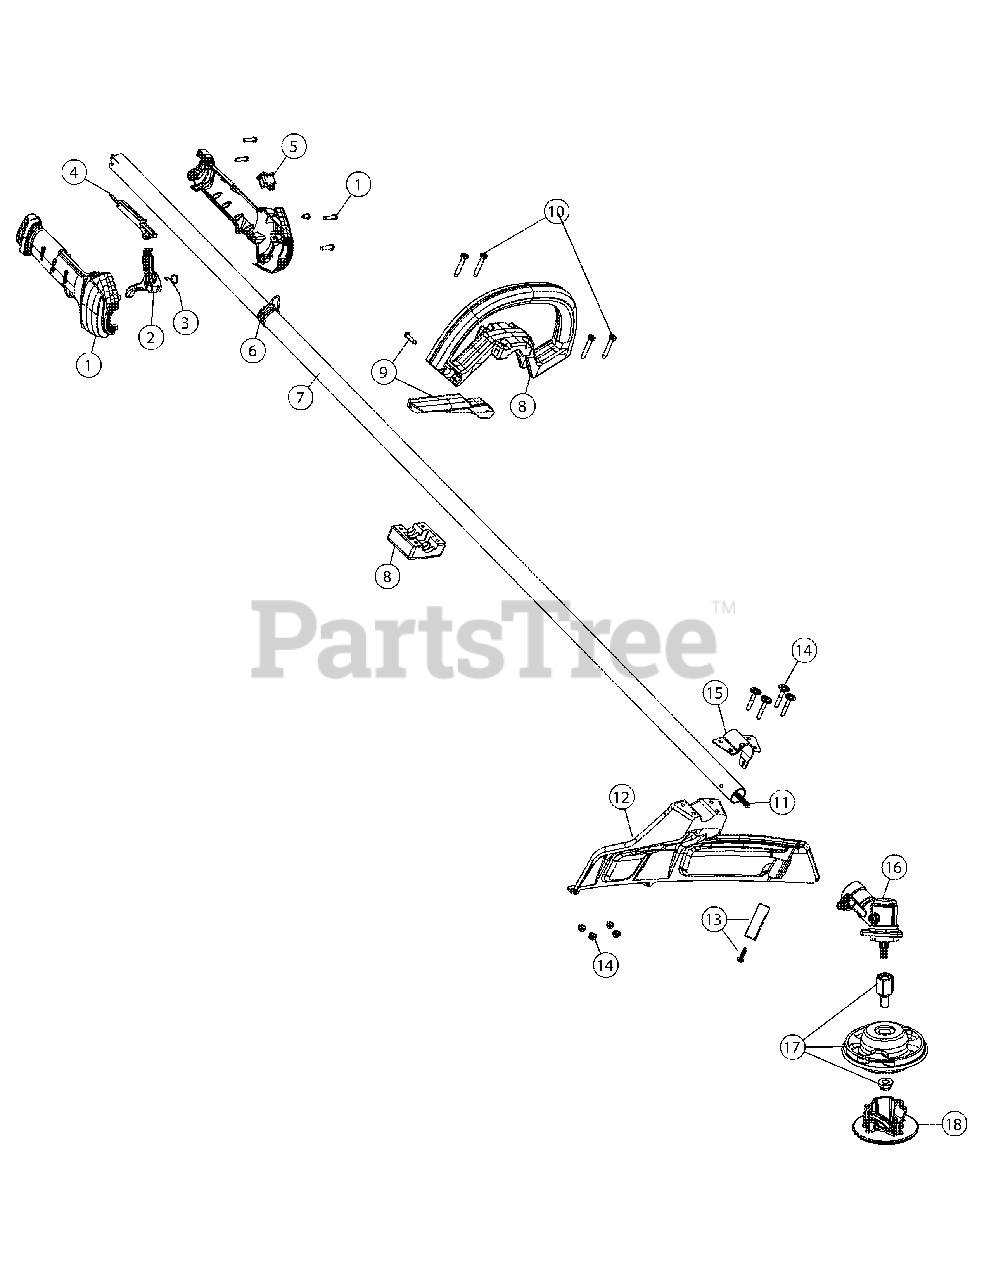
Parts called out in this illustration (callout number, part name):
1	Throttle Housing Assembly
2	Throttle Trigger
3	Spring
4	Throttle Lock-out
6	Shoulder Strap Clip
7	Driver Shaft Housing
8	D-Handle Assembly
9	Barrier Bar Assembly
11	Solid Drive Shaft
12	Shield Assembly
13	Blade Assembly
14	Guard Mounting Hardware
15	Guard Mounting Bracket
16	Gearbox
17	Cutting Head Assembly
18	Cutting Head Cap
